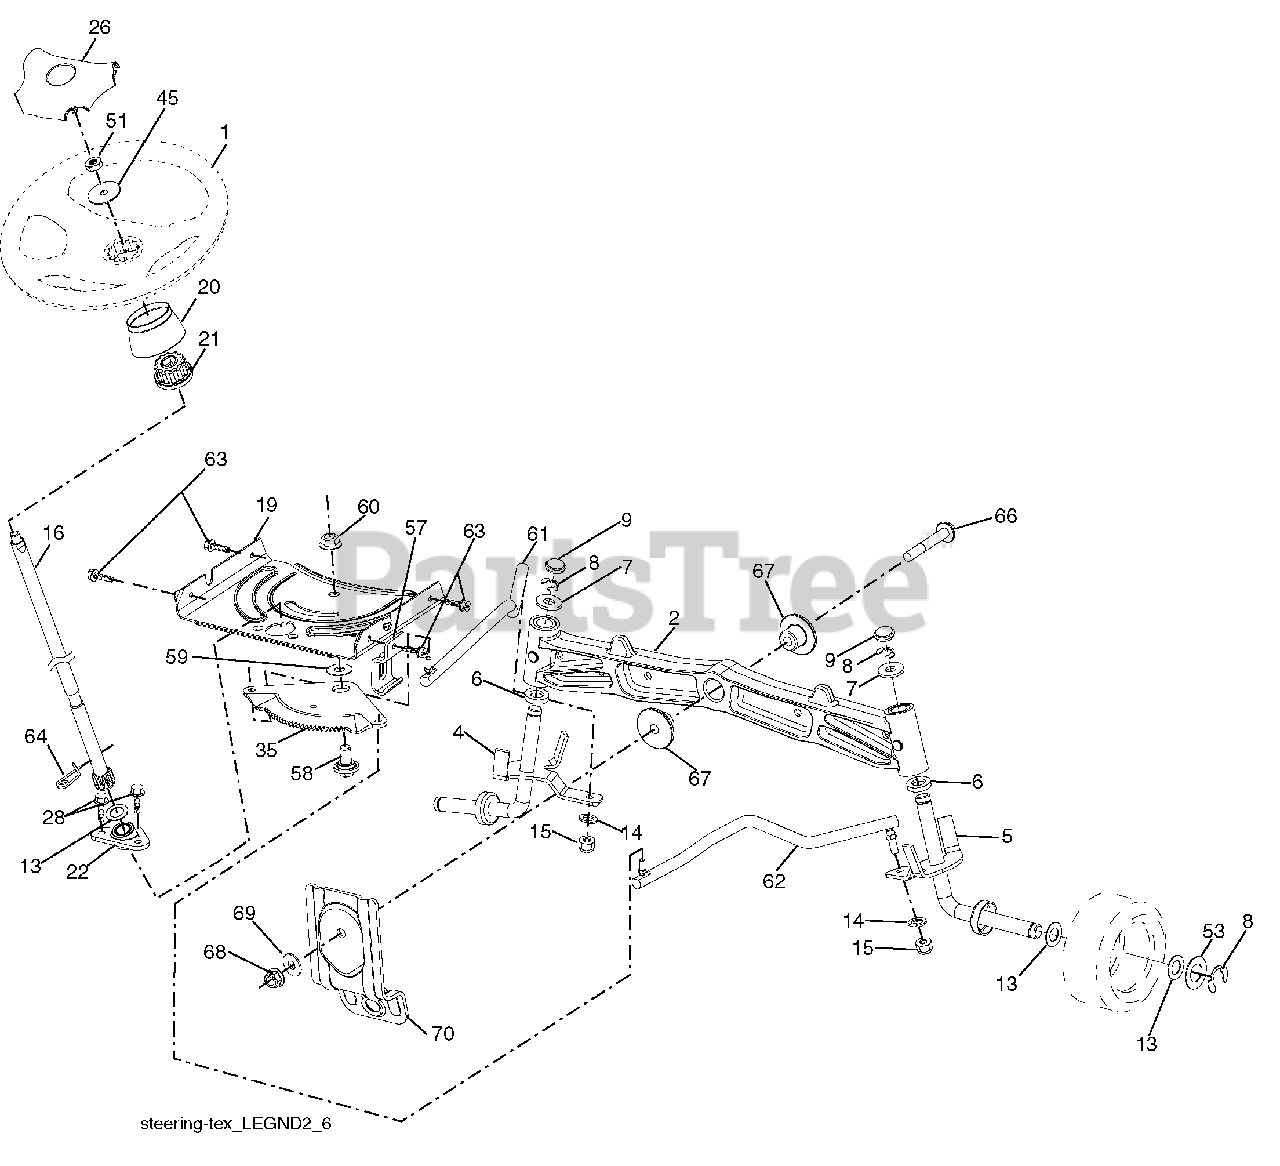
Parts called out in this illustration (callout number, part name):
1	Wheel, Steering
2	Axle Asm., Front
4	Spindle Asm., LH
5	Spindle Asm., RH
6	Bearing, Race Thrust Harden
7	Washer 25/32 x 1-5/8 x 16 Ga.
8	Ring, Klip #T5304-75
9	Cap, Spindle
13	Washer 25/32 x 1-1/4 x 16 Ga.
14	Washer, Lock Hvy Hlcl Spr 3/8
15	Nut, Crown Lock 3/8-24 unf
16	Shaft Steering
19	Plate Steering
20	Boot, Steering
21	Adapter, Wheel Steering
22	Supt, Strg. Lower
26	Insert, Wheel Steering
28	Screw 3/8-16 x 3/4
35	Gear, Sector Plate
45	Washer 9/16 ID x 2-3/8 OD 12 GZIN
51	Nut Hex Jam Toplock 1/2-20 unf
53	Washer Hardened .793 x 1.637 x .060
57	Bracket Upstop
58	Bolt Shoulder Sector Pivot CFM
59	Washer Thrust Sector Steering
60	Nut Flange Lock 5/8-11
61	Draglink LH
62	Draglink, RH
63	Screw 5/16-18 x 3/4
64	Retainer Clip Spring Steering
66	Bolt Hex Fghd 7/16-14 x 3 Serr
67	Bushing PM Front Axle
68	Nut Lock Flange 7/16-14 Gr. 5
69	Washer 1.5 x .505 x .118
70	Bracket Deck Susp. Front
